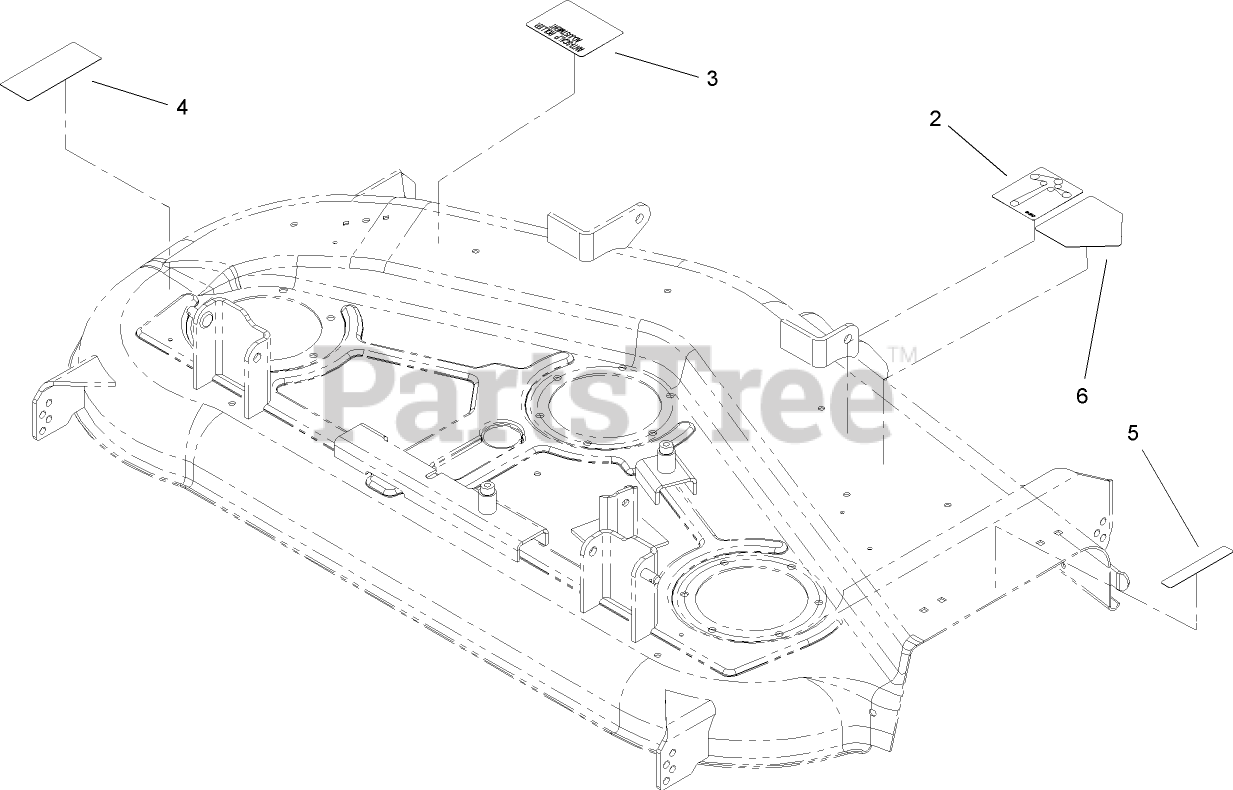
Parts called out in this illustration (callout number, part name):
2	DECAL-ROUTING, BELT
3	DECAL-WHEEL, GAGE
4	DECAL-DANGER
5	DECAL-CAUTION
6	DECAL-DANGER
